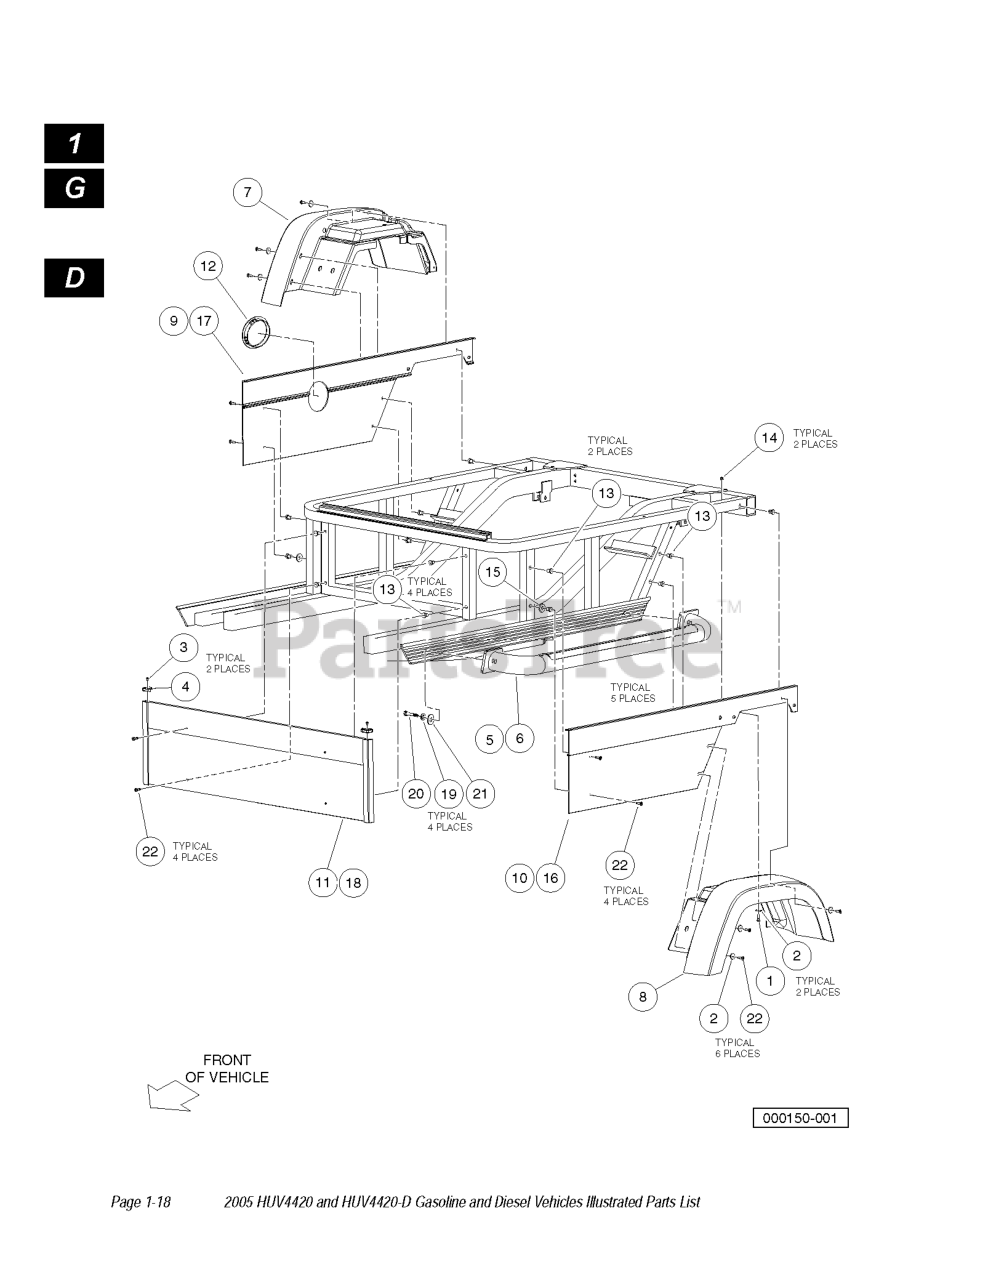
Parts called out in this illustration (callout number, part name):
4	CORNER CAP AWD
5	SIDE STEP BAR
6	SIDE STEP BAR
7	FENDER, RIGHT REAR
8	FENDER, LEFT REAR
9	PANEL, SIDE, WELDMENT, PASS
10	PANEL, SIDE, WELDMENT, DRV
11	PANEL, FRONT, WELDMENT
12	BEZEL, FUEL FILL
13	WELL NUT 1/4-20
14	NUT FLG, M6 X 1.0 NYLON
15	WASHER, M12 HARD REGULAR
16	SIDE PANEL, DRIVER, ORANGE
17	SIDE PANEL, PASS, ORANGE
18	FRONT PANEL ORANGE
19	WASHER,LOCK,HEL SP 3/8 REG
20	BOLT, 3/8-16 X 3.00 HEX HEAD
21	WASHER, 3/8 TYPE B FLAT
22	SCREW, 1/4-20 X 1.0 TRS HD MCH
